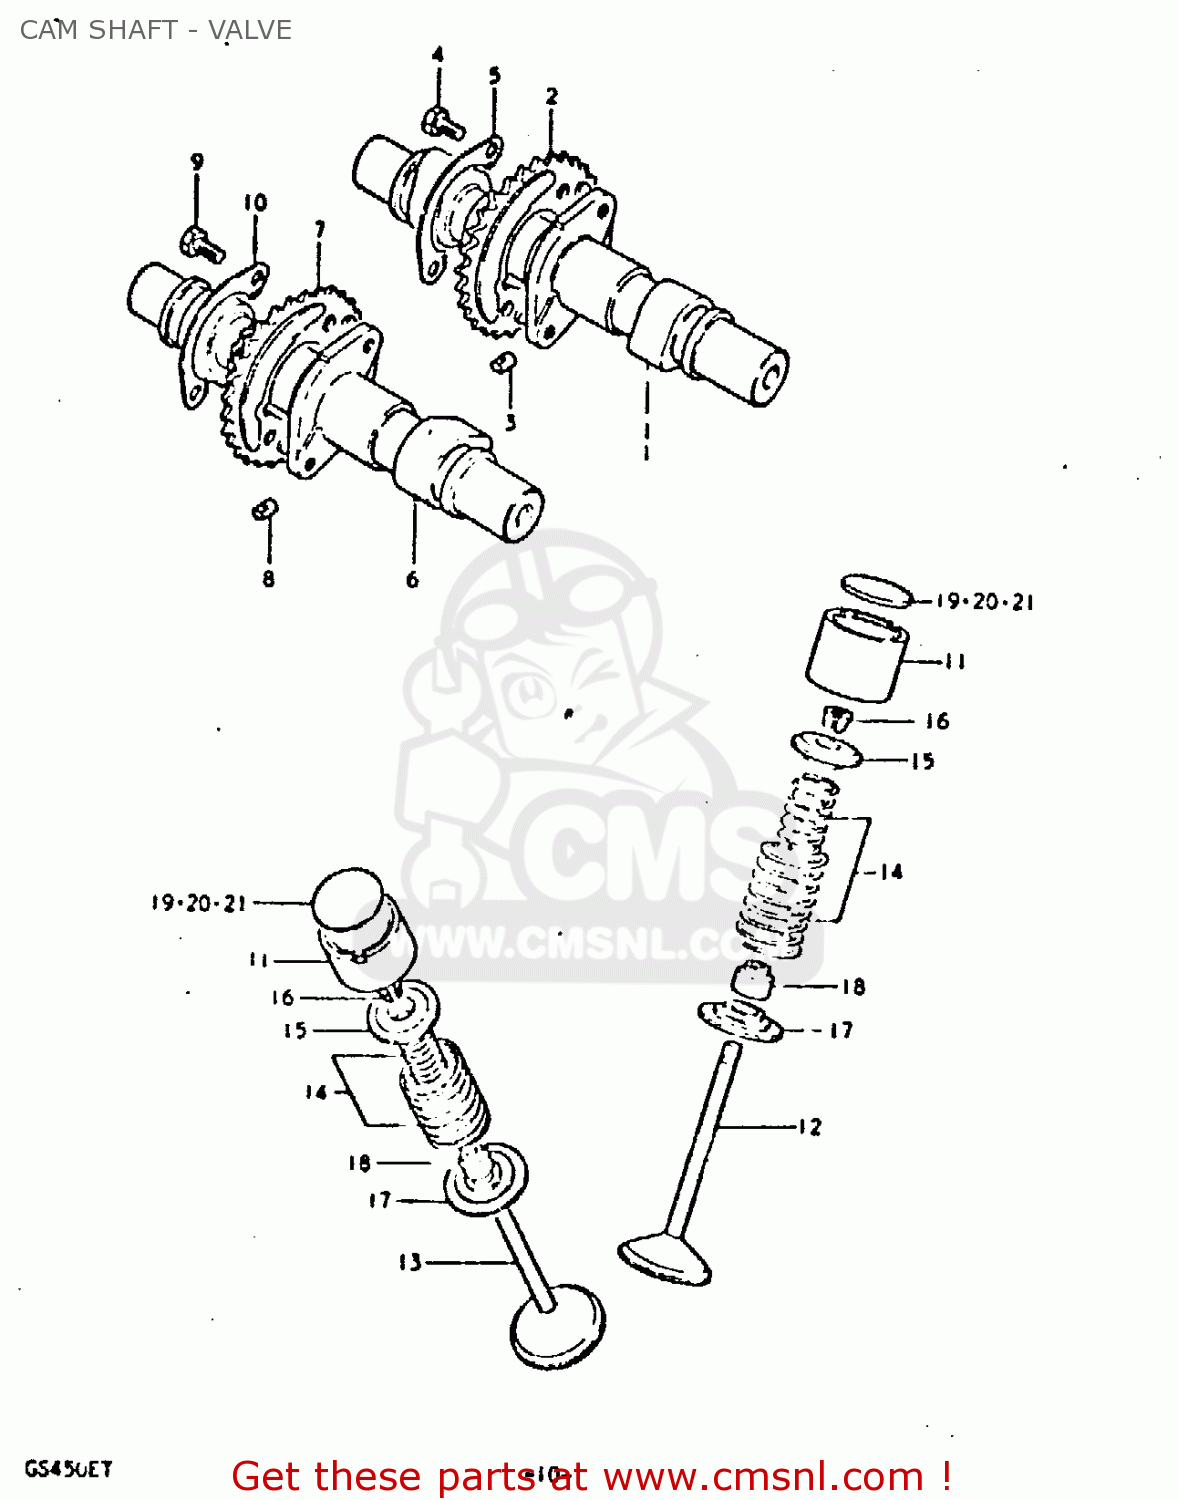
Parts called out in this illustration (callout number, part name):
1	CAMSHAFT,INTAKE
2	SPROCKET,CAMSHAFT
3	PIN,SPROCKET
4	BOLT(6X12.5)
5	WASHER,CAM CHAIN SPROCKET
6	CAMSHAFT,EXHAUST
7	SPROCKET,EXHAUST CAM(NT:30)
8	PIN,SPROCKET
9	BOLT(6X12.5)
10	WASHER,CAM CHAIN SPROCKET
11	TAPPET
12	VALVE,INTAKE
13	VALVE,EXHAUST
14	SHIM,TAPPET
15	RETAINER,VALVE SPRING
16	COTTER VALVE
17	SEAT,VALVE SPRING
18	SEAL,OIL(7X14.4X9)
19	SHIM,TAPPET
20	SHIM,TAPPET
21	SHIM,TAPPET
